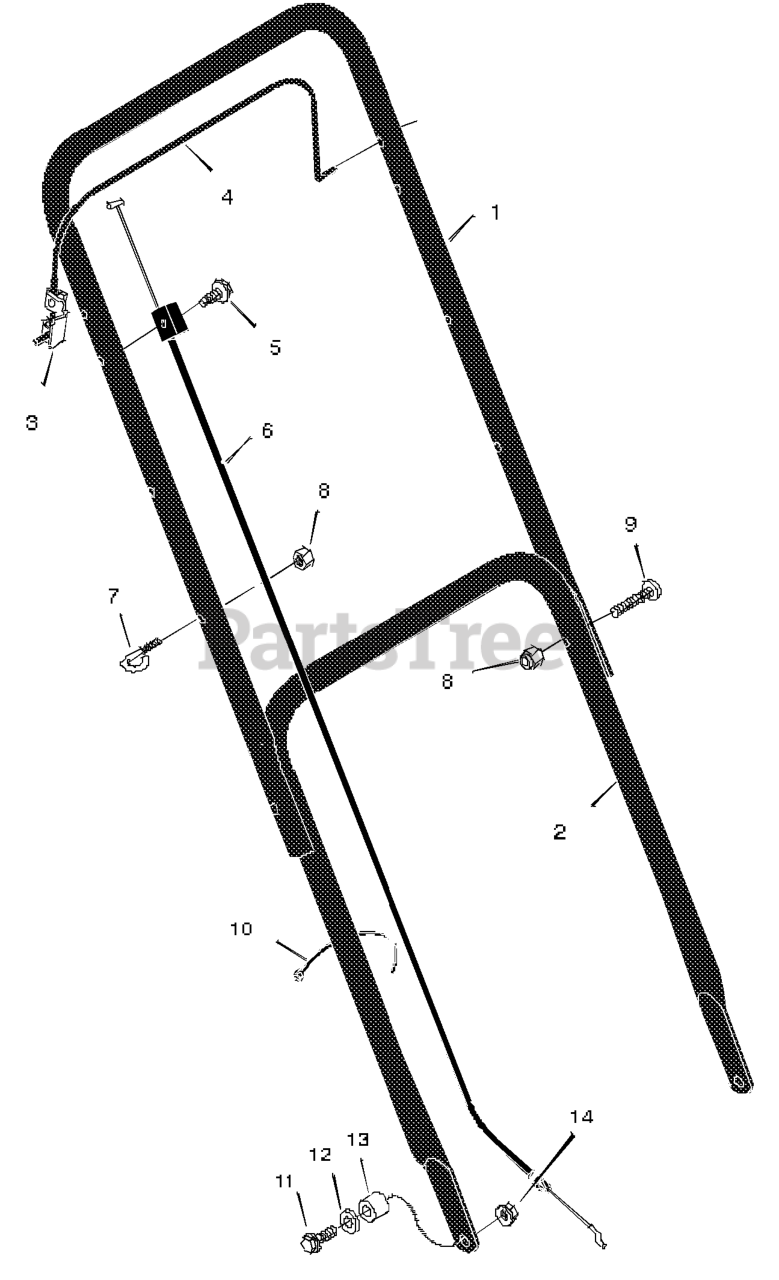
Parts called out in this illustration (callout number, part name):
1	Handle, Upper
2	Handle, Lower
3	Bracket, Stop Lever
4	Lever, Stop
6	Engine Stop Cable
7	GUIDE, ROPE
8	Locknut
10	Fastener, Cable
11	Bolt
14	Nut
